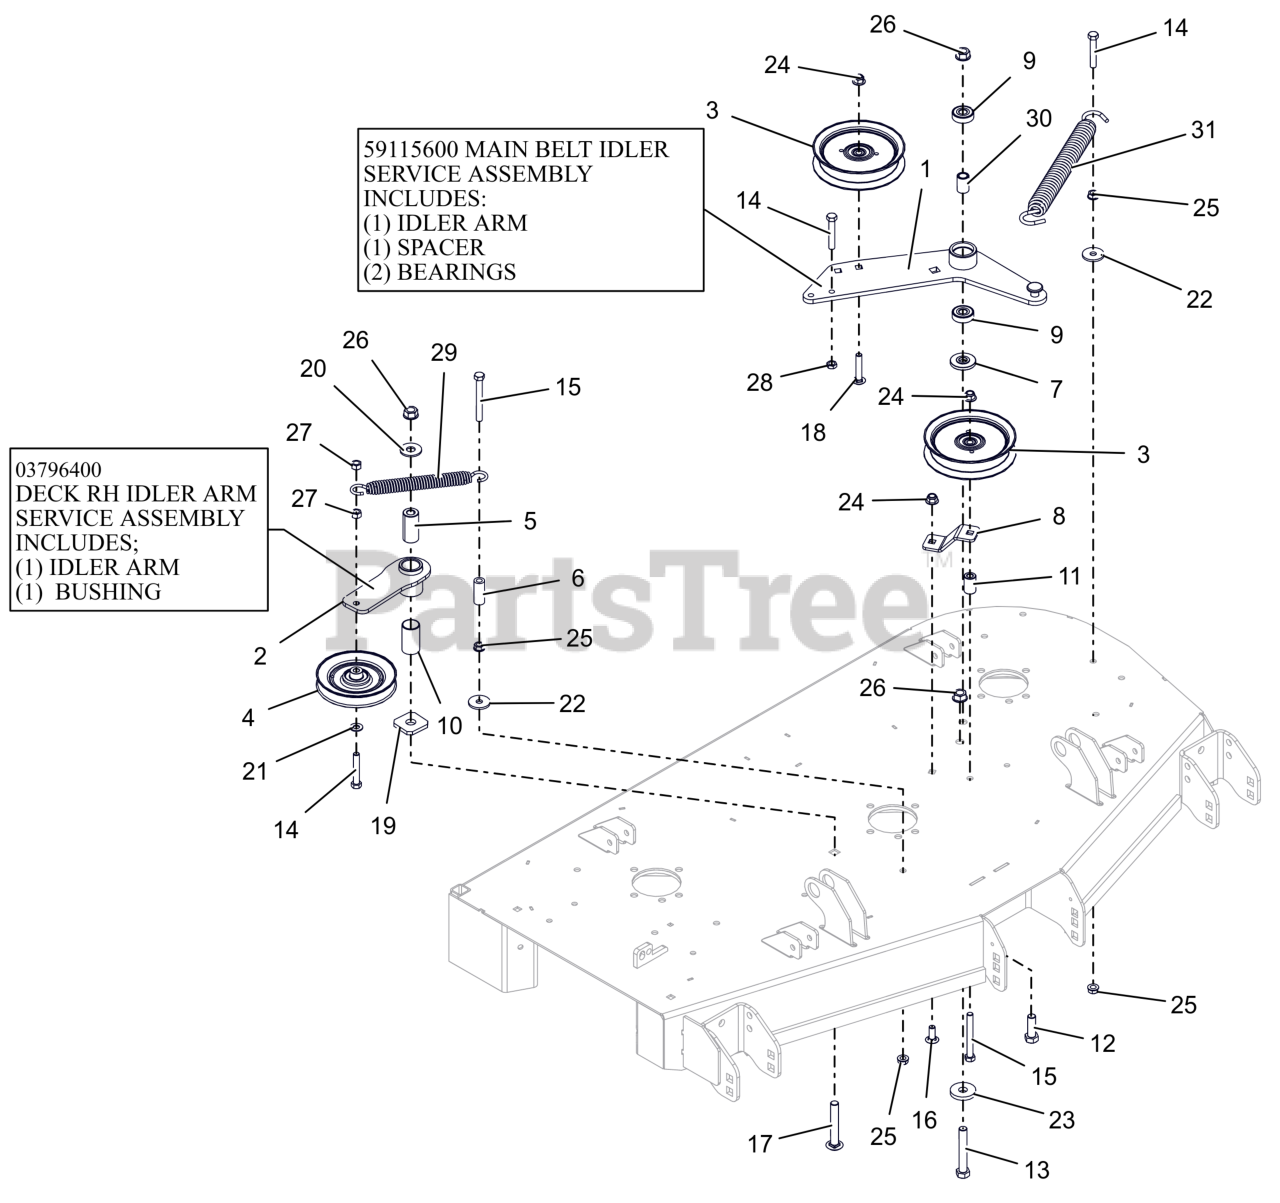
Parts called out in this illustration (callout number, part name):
1	WLDMT, DECK PTO IDLR ARM
1	ASM, IDLER ARM (DECK)
2	WMT, IDLER ARM - BLACK
2	ASSEMBLY, MAIN BELT IDLER
3	IDLER, FLAT 5.00"
4	IDLER, V-5.00"
5	BSHG, SPCR .502X.997X2.03 PM
6	HOSE, .38 X 1.65
7	SPACER, IDLER ARM
8	PTO FIXED IDLER MTG BRKT -RED
9	BRG-BALL .500X1.38X.437
10	BSHG, 1.00X1.125X1.937
11	BUSHING, SLV .380X.750X1.190
12	BLT,HEX .50-13X1.50 G5 ZCC
13	BLT,HEX .50-13X3.25 G5 ZCC
14	BLT,HEX .38-16X2.25 G5 ZCC
15	BLT, HEX .38-16X3.25 G5 ZCC
16	BLT,RHSSN .38-16X1.00 G5 ZCC
17	BTL,RHSSN .500-13 X 3.25 G5 ZCC
18	BLT,RHSSN.375-16X2.00 G5 ZCC
19	WSHR-FLT .640X1.75X.250
20	WSHR,FLT .563X1.375X.109 ZCC
21	WSHR,FLT .406X.812X.065 ZCC
22	WSHR,FLT .406X1.375X.135 ZCC
23	WSHR-FL-STL 0.557X1.625X0.25 ZCC
24	NUT,NYL-FLG .38-16 GF ZCC
25	NUT, SPNLK-FLG .38-16 G5 ZCC
26	NUT-LK-CTR-FLG .500-13 GG ZCC
27	NUT-LK-CTR .38-16 ZC120
28	NUT-JAM .375-16 G2 ZCC
29	SPRING, EXTENSION
30	SPACER .510 X .75 X 1.1485
31	SPRING, EXTENSION
